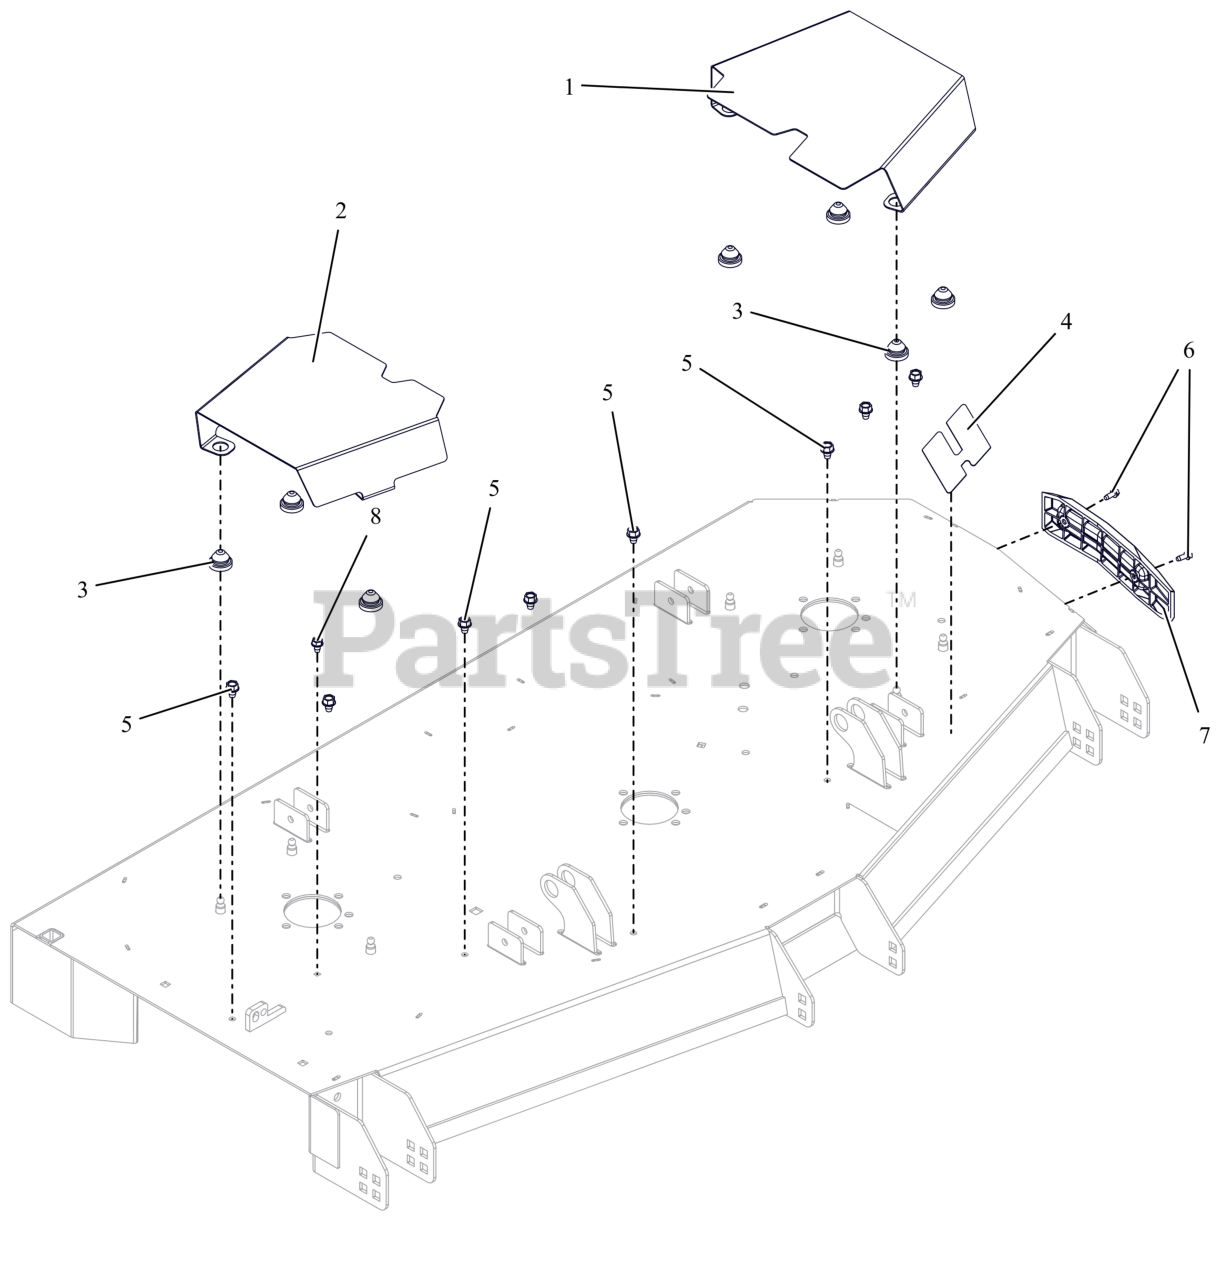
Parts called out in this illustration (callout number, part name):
1	COVER- BELT 60" LEFT
2	COVER- BELT 60" RIGHT
3	COUPLING, RUBBER PUSH-IN
4	GRIP- STEP ANTISKID HD STEALTH
5	SCR,TAP .375-16X.50 HWH TR ZCC
6	SCR,TAP .25-20X.625 HWH ZCC
7	BUMPER- DECK
8	SCR,TAP .312-18X.50 HWH TR ZCC
